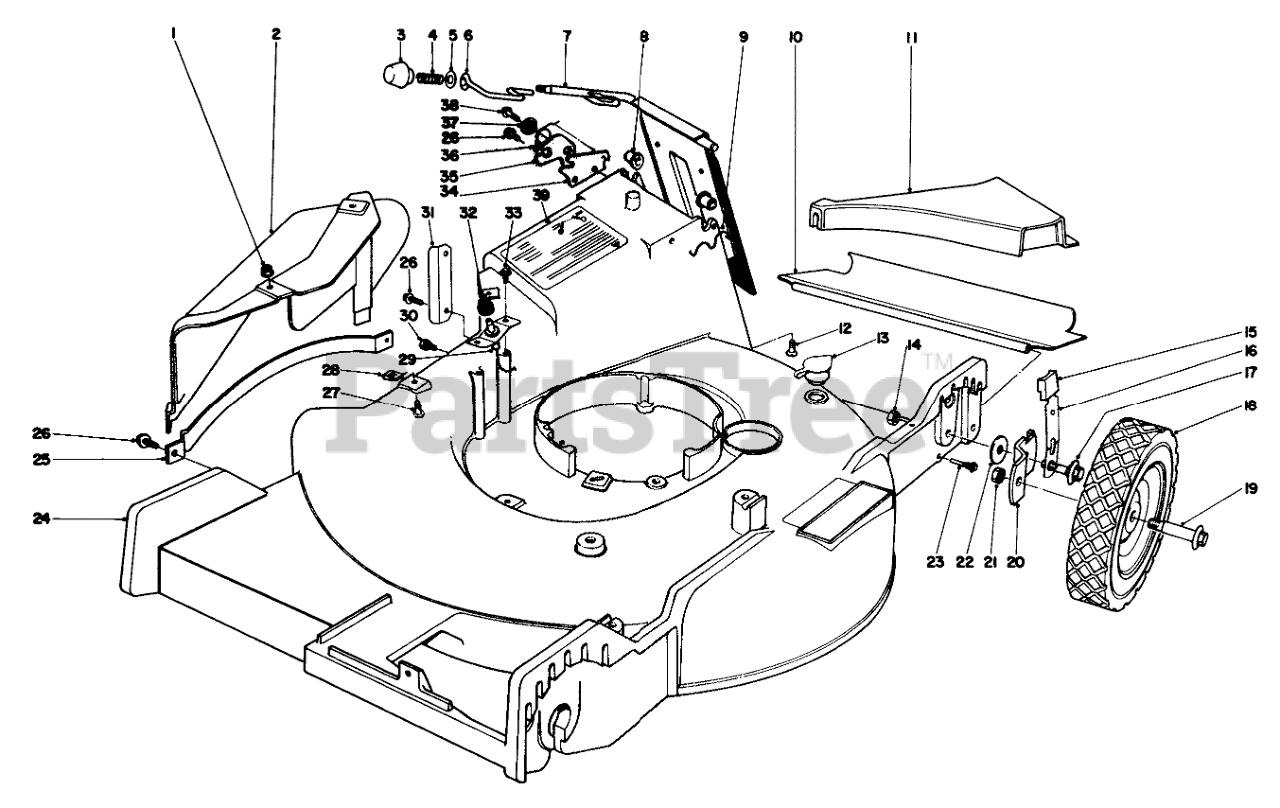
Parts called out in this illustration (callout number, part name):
1	NUT-HF
2	DEFLECTOR
4	COMPRESSION SPRING
5	WASHER
6	DOOR LATCH
7	Door Handle
8	BUSHING-NYLON
9	Door Retainer
10	REAR SAFETY SHIELD
11	REAR INSERT
12	SCREW-HH
13	WASHOUT PLUG
14	Nut
15	Arm Knob
16	SPRING ARM ASM
17	PIVOT SCREW
18	Wheel Assembly
20	PIVOT ARM PLATED
21	Nut
22	WASHER-PIVOT
23	SAFTEY SHIELD SCREW
24	Housing
25	Bar Safety
26	SCREW
27	NUT-SPEED
29	Deflector Switch (Incl. Ref. #32)
30	SCREW THD 1/4 20 5/8
31	Clip Retaining
32	Boot Switch
34	DOOR LATCH PLATE
35	Latch Safety
36	TORSION SPRING
37	Latch Spacer
38	Screw
39	Decal-Caution
